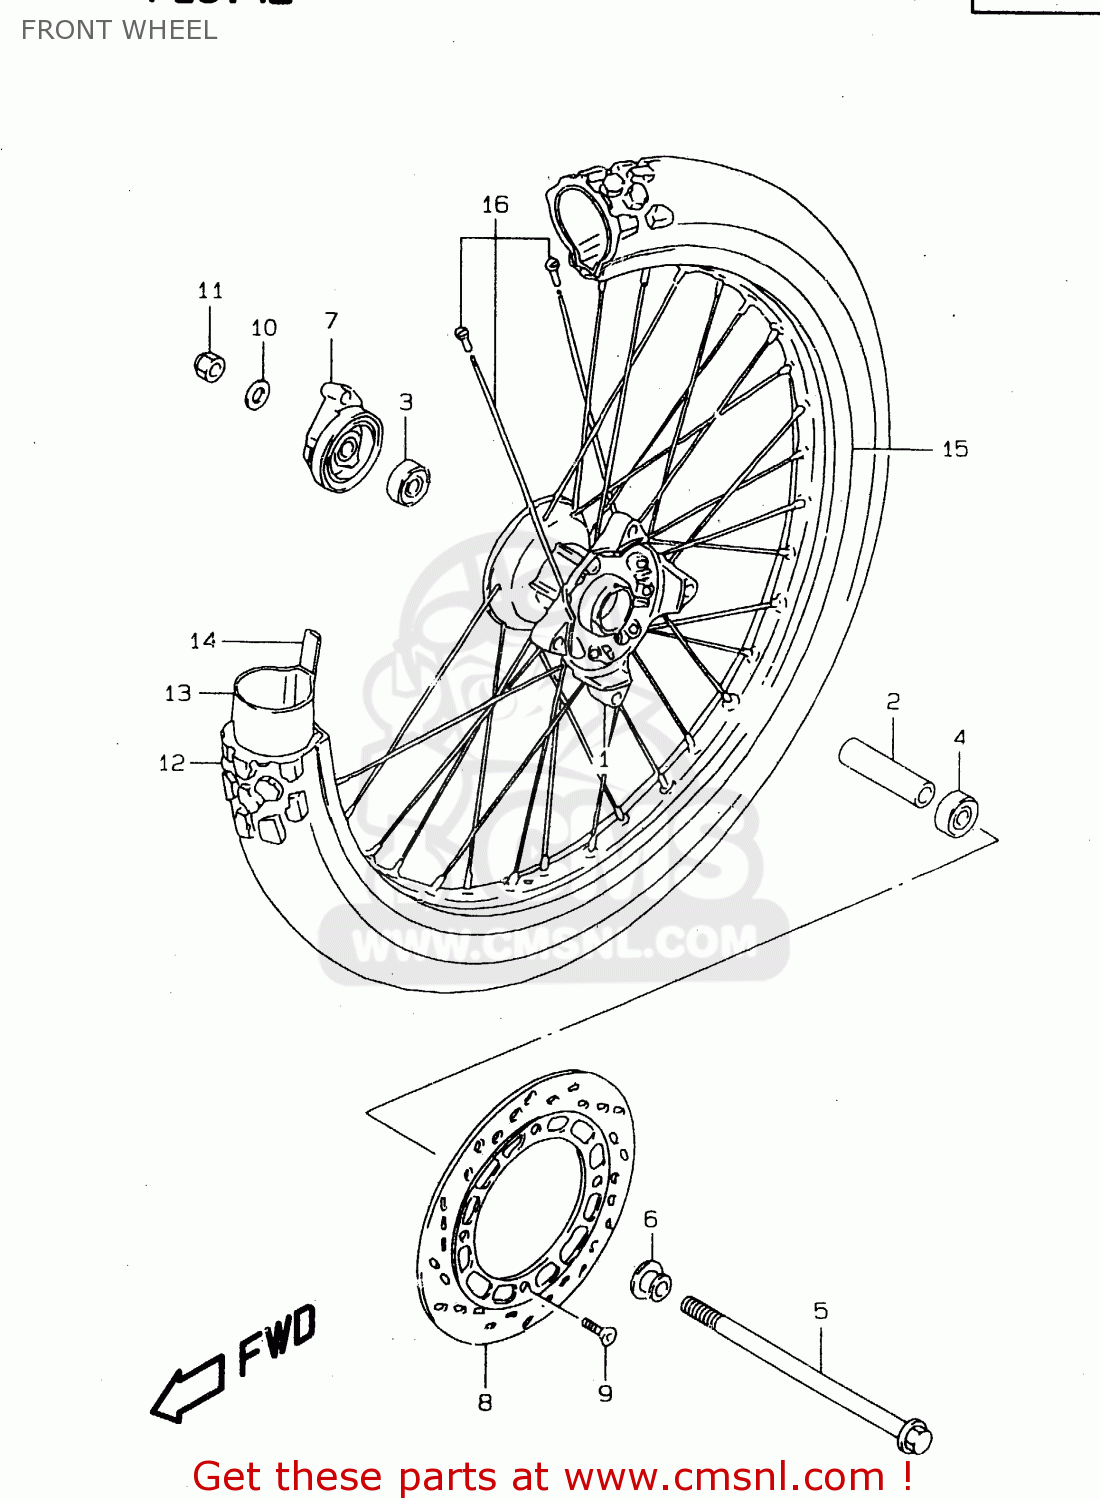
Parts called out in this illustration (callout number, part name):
1	HUB,FR
2	SPACER(12.5X19X60.5)
3	BEARING
4	BEARING (12X32X10)
5	AXLE,FR
6	SPACER,FR AXLE
7	BOX ASSY,SPEEDOMETER GEAR
8	DISC,FR BRAKE
9	BOLT,BRAKE DISC
10	WASHER
11	NUT 12MM
12	TIRE,FR(70/100-21 44P)
13	TUBE
14	PROTECTOR,WHEEL INNER
15	RIM,FR WHEEL(21X1.60 FE)
16	SPOKE SET,FR WHEEL
